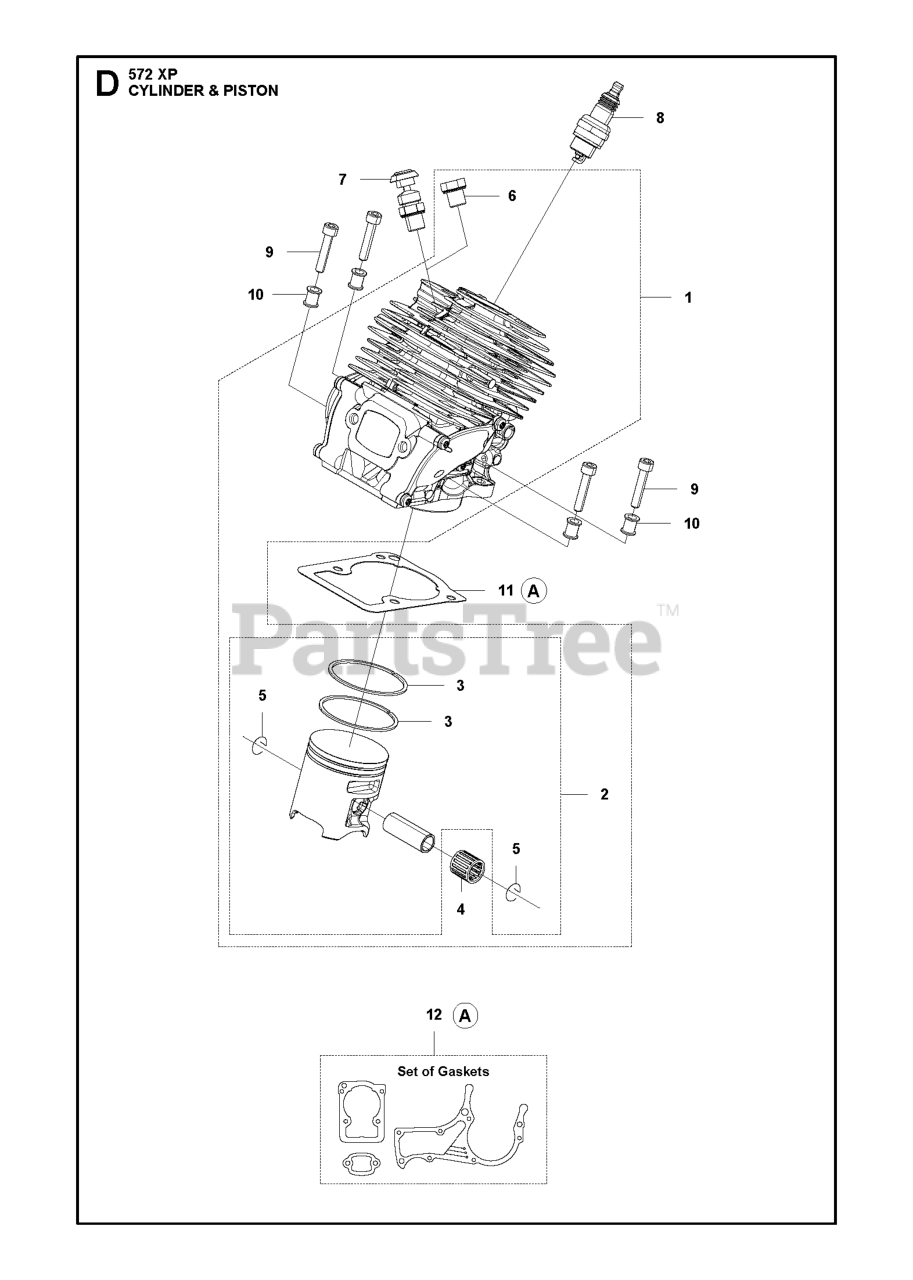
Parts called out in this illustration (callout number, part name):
1	CYLINDER ASSY SPARE PART H572
2	PISTON ASSY D48 M145 (SPARE PA
3	PISTON RING
4	NEEDLE BEARING PISTON PIN 12X1
5	WRIST PIN CLIP
6	CYLINDER PLUG
8	SPARK PLUG M14X1.25 NGK BPMR7A
9	SCREW ITXSCM
10	SLEEVE H572
11	GASKET CYLINDER
12	GASKET KIT H565/H572
